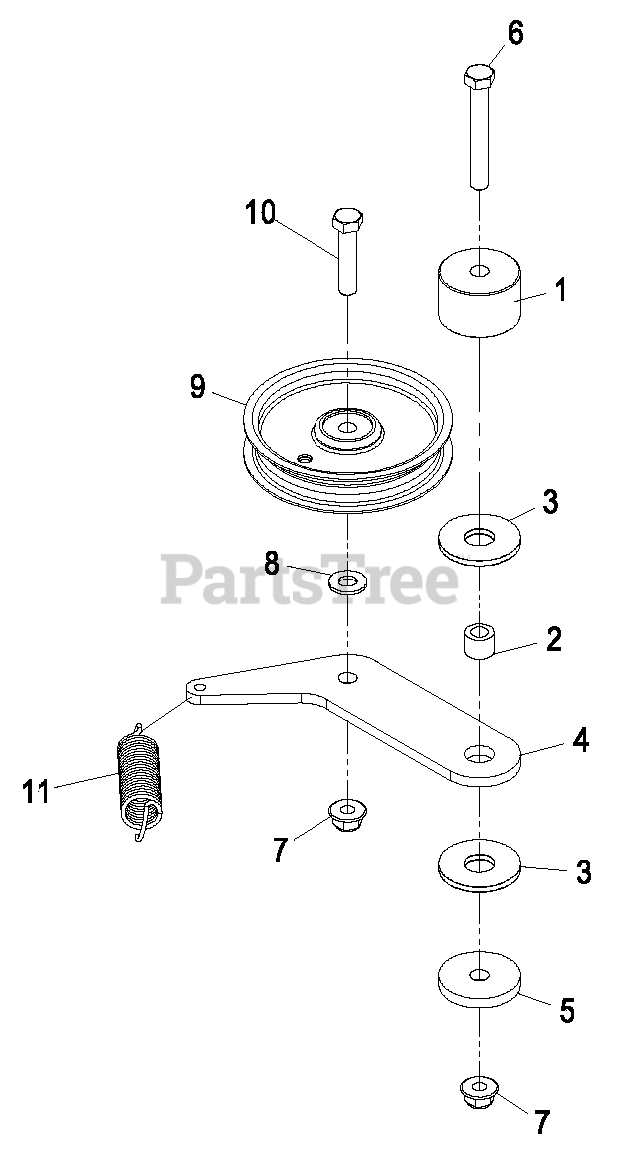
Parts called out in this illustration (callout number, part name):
1	HUB-IDLER
2	BUSHING-LEVER, LIFT
3	WASHER-FRICTION, COMPOSIT
4	PLATE-IDLER
5	WASHER-PLAIN
6	SCREW-HH
7	NUT-HF, NI
8	WASHER-FLAT
9	PULLEY-IDLER
10	SCREW-HH
11	SPRING-EXTENSION
